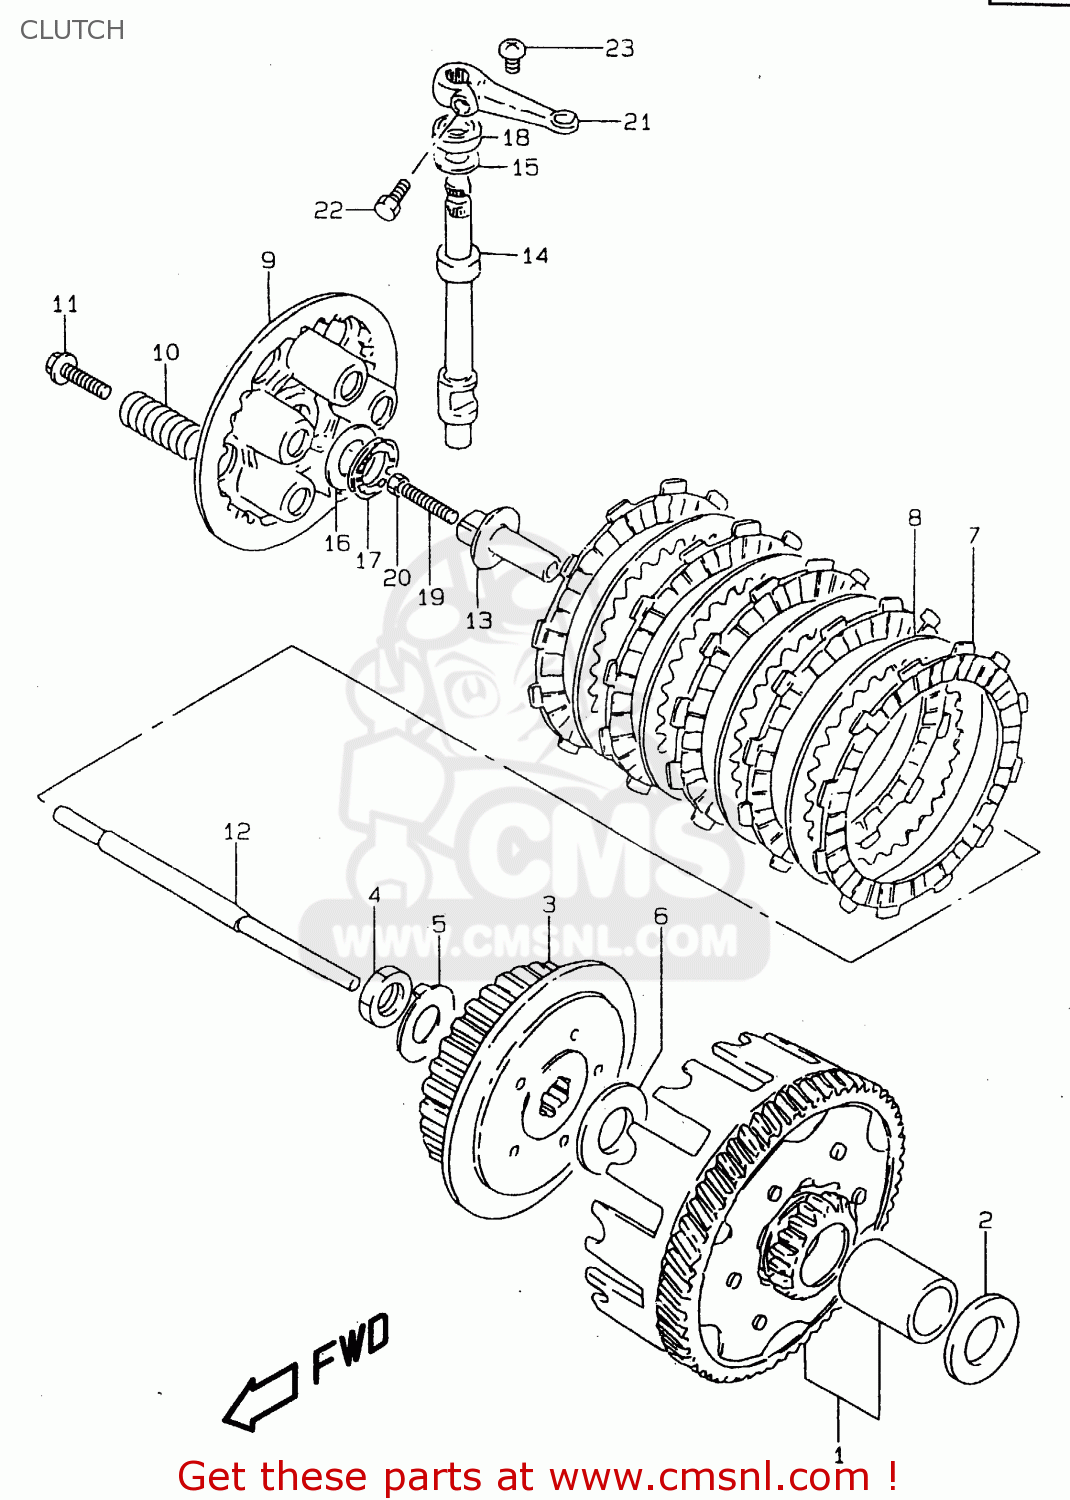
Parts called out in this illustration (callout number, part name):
1	GEAR ASSY,PRIMARY(NT:20/59)
2	WASHER
3	HUB,CLUTCH SLEEVE
4	NUT
5	WASHER
6	WASHER
7	PLATE,CLUTCH DRIVE(T:3.0) (NAS)
8	PLATE,CLUTCH DRIVEN (NAS)
9	PLATE,CLUTCH PRESSURE
10	SPRING
11	BOLT(5X16)
12	ROD,CLUTCH PUSH
13	PIECE,CLUTCH PUSH
14	CAMSHAFT,CLUTCH RELEASE
15	SHIM(10X20X1)
16	WASHER(15.5X28X1)
17	BEARING(15X28X2)
18	SEAL,OIL(10X20X6)
19	SCREW(6X25)
20	NUT
21	ARM,CLUTCH RELEASE
22	BOLT
23	SCREW 6X10
